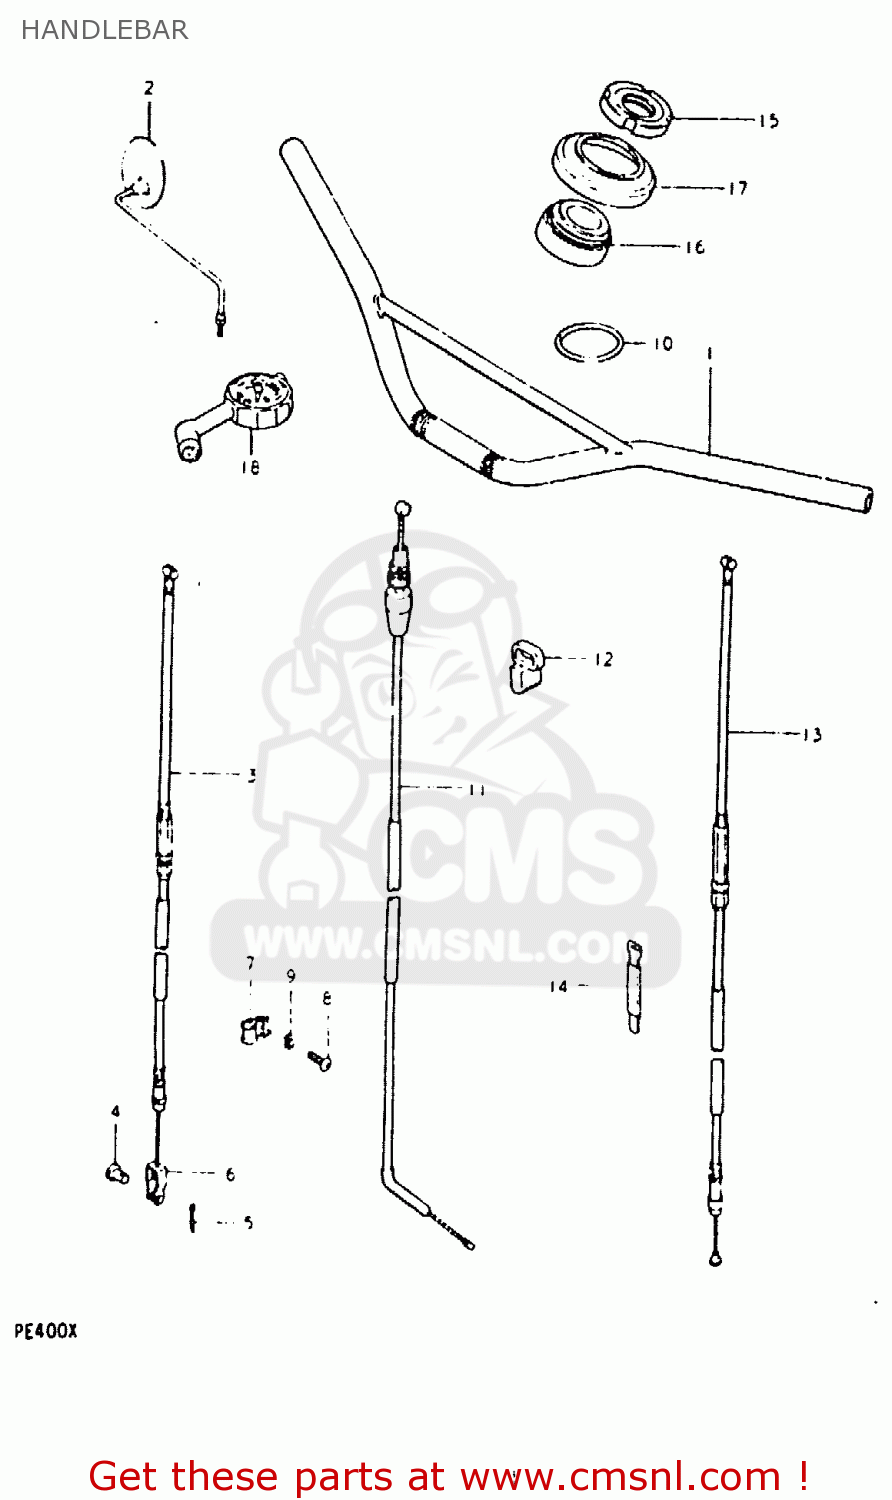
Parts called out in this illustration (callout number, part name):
1	HANDLEBAR
3	CABLE,FRONT BRAKE
4	PIN(L:13.5)
5	PIN
6	BRAKE CABLE HOOK
7	GUIDE,CABLE
8	SCREW
9	LOCK WASHER
10	O RING(D:3.53,ID:69.44)
11	CABLE ASSEMBLY,THROTTLE
12	GUIDE,CABLE
13	CABLE,CLUTCH
14	CLAMP
15	NUT,STEERING STEM(25X44X10)
16	TAPER,ROLLER BEARING
17	DUST SEAL,STEERING,UPPER
18	GAUGE ASSY,AIR PRESSURE
